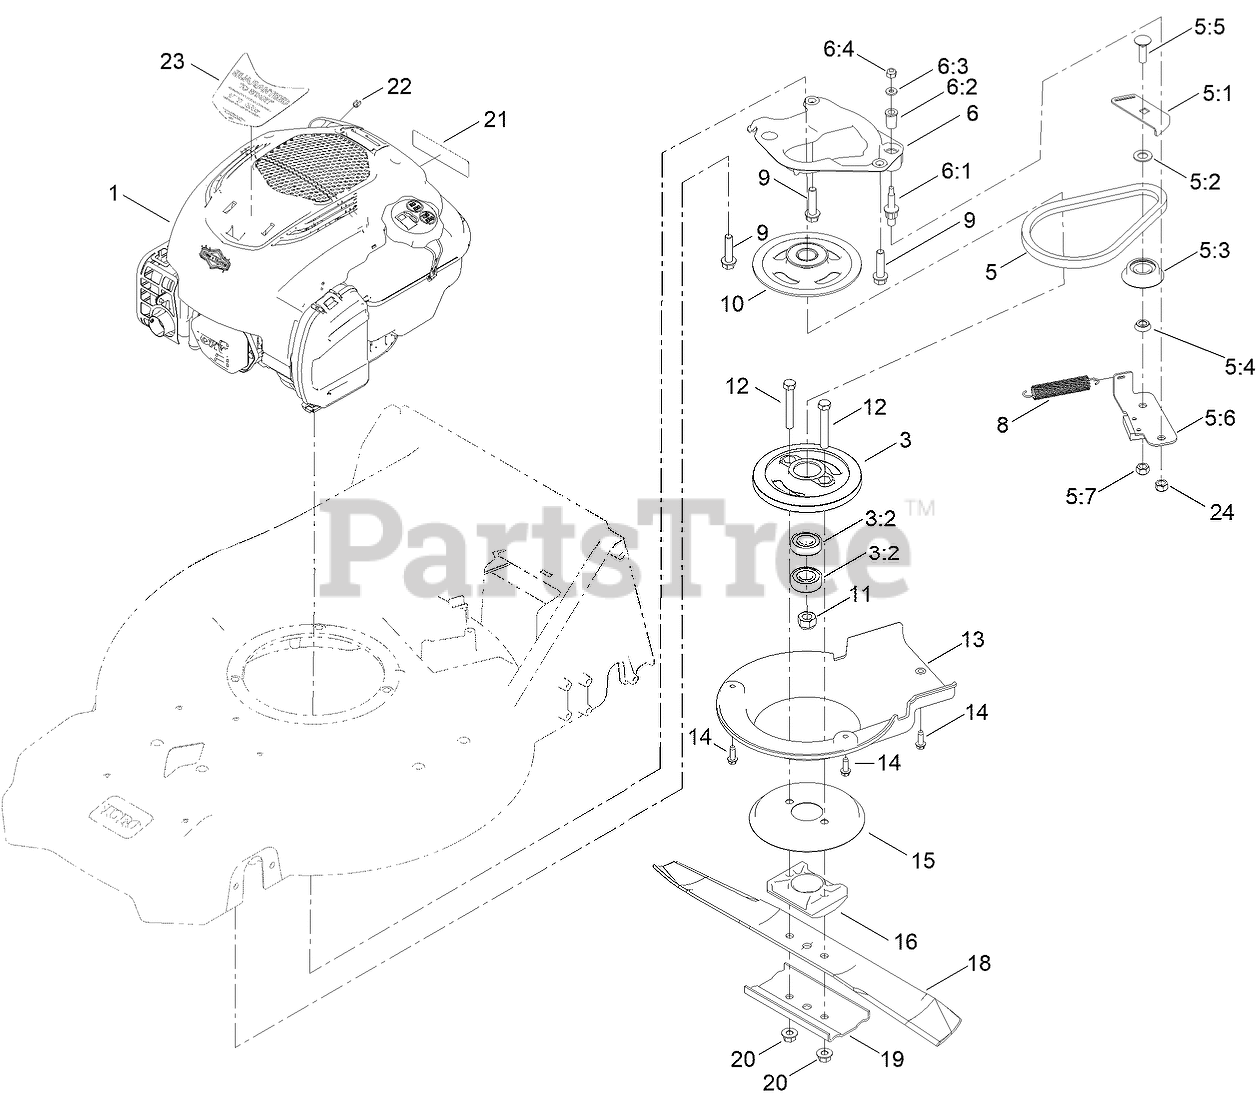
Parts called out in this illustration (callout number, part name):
1	ENGINE-BRIGGS 725 EXI BBC
3	DRUM-BBC
3:2	BEARING-BALL
5	BRAKE-BBC
5:1	BELT
5:2	PLATE-GUIDE
5:3	SPACER
5:4	RETAINER-BBC
5:5	SPACER-BEARING
5:6	BOLT-CARR
5:7	PLATE-BRAKE
6	PLATE-ANCHOR,BBC
6:1	PLATE-ANCHOR
6:2	BOLT-SHOULDER
6:3	BUSHING
6:4	WASHER-FLAT
8	SPRING-TENSION, BRAKE
9	SCREW-HWH
10	PULLEY
11	NUT-HEX
12	SCREW-HH
14	SCREW-HWHTF
16	SUPPORT-BLADE
18	BLADE-21IN, RECYCLING
19	SUPPORT-BLADE
20	NUT-FLANGE, LOCK
21	DECAL-ARRESTOR, SPARK
22	STOP-ROPE
23	DECAL-BRIGGS, 163CC BBC
24	LOCKNUT
